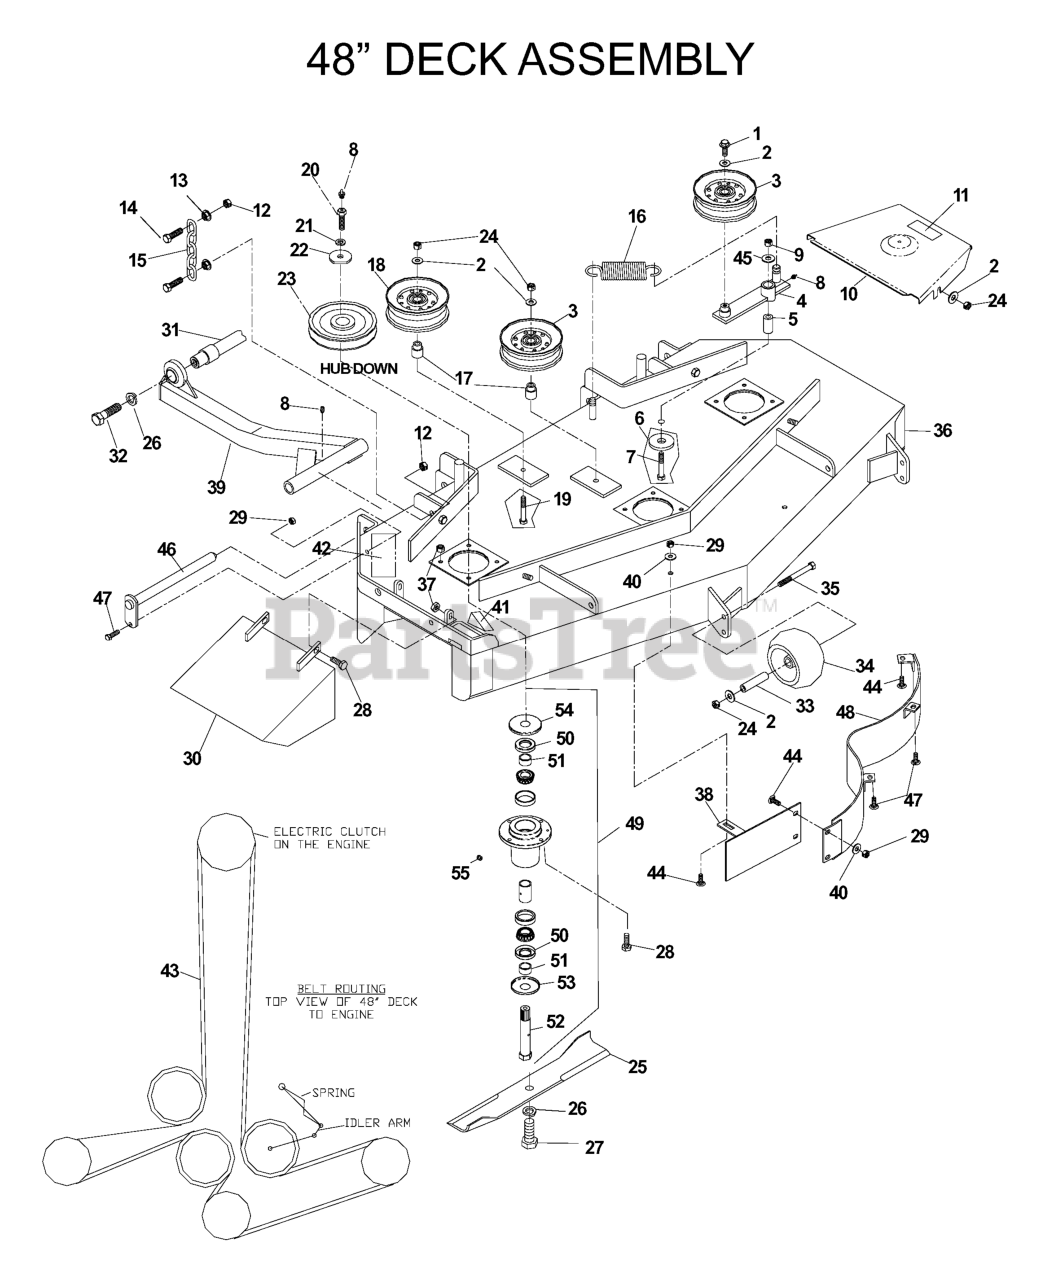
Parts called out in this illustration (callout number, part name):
1	4CS 3/8C X 1 SERRATED HEAD
2	WASHER 3/8 FLAT
3	IDLER PULLEY
5	PIVOT BUSHING
6	WASHER, SUPPORT
7	HCS 1/2C X 3 1/4
8	ZERK
9	NUT 1/2-13 HEX NYLOC ZD
10	LT 48 SHIELD, ORG
11	DECAL, NO STEP
12	NUT 7/16C CENTERLOCK
13	NUT 7/16C WHIZ
14	HCS 7/16C X 1 1/2
15	LIFT CHAIN
17	IDLER BUSHING
18	IDLER PULLEY (TALL)
19	SCREW 3/8C X 2 3/4 HEX CAP
20	DRILLED BOLT 7/16-20 X 1 1/2"
21	WASHER 7/16 LOCK
22	SPINDLE WASHER
23	RP PULLEY - 42/48"
24	NUT 3/8-16 NYLOC
25	BLADE OEM 16 1/4"
26	LOCKWASHER 5/8
27	HCS 5/8F X 1 1/4
28	HCS 5/16C X 1 1/4
29	NUT 5/16C CENTERLOCK
30	CHUTE 48"
31	STRUT MOUNT WELDMENT
32	HCS 5/8C X 2 GR.5
34	ANTI-SCALP ROLLER
35	HCS 3/8C X 3 1/2
36	DECK W/DECALS 48"
37	NUT 5/16 NYLOC
38	CENTER BAFFLE 48"
39	STRUT WLDMT - RT
40	WASHER 5/16 FLAT
41	DECAL, CPSC
42	DECAL, DANGER
43	DECK BELT 48"
44	CARRIAGE BOLT 5/16C X 5/8"
45	WASHER 1/2 FLAT
47	HCS 5/16C X 3/4
48	MAIN BAFFLE - 48" DECK BLK
49	SPINDLE ASSY - 42/48"
50	SHAFT SEAL
52	SPLINED SHAFT - 42/48"
53	BOTTOM DUST CAP
54	TOP DUST CAP
55	PLUG-VENTED
539104621	STRUT SLDMT-LT
539108902	RT 48 SHIELD, ORG
